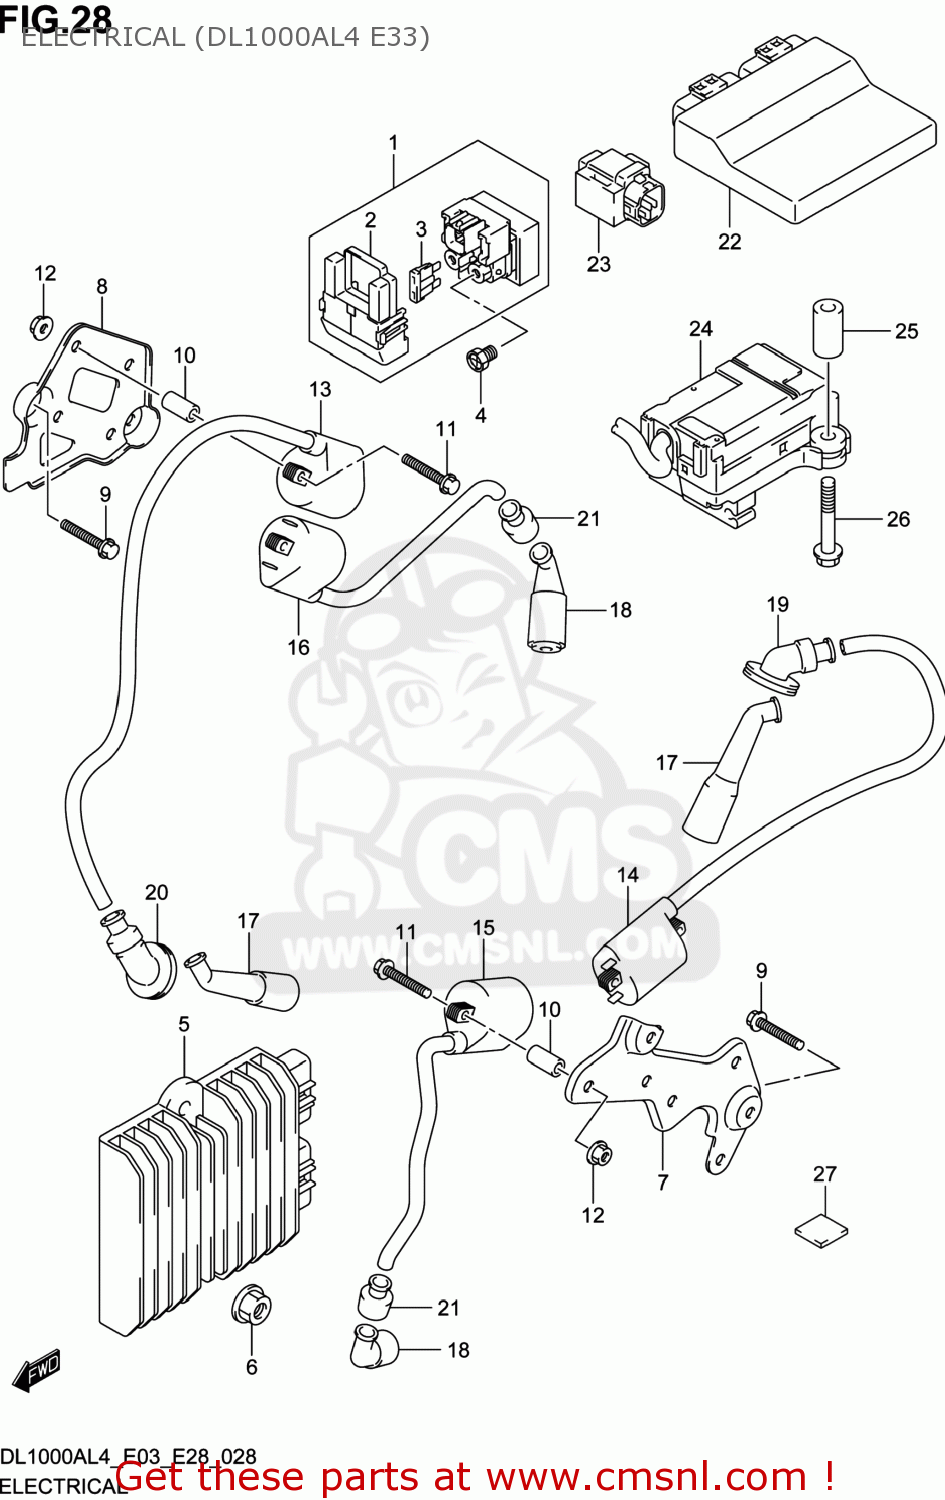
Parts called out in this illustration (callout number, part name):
1	RELAY ASSY,STARTING MOTOR
2	COVER
3	FUSE(30A)
4	SCREW(6X8)
5	RECTIFIER ASSY
6	NUT
7	BRACKET,IGNITION COIL
8	BRACKET,IGNITION COIL
9	BOLT
10	SPACER(6.4X10X18)
11	BOLT(6X35)
12	NUT
13	COIL ASSY,IGNITION
14	COIL ASSY,IGNITION
15	COIL ASSY,IGNITION
16	COIL ASSY,IGNITION
17	CAP ASSY,SPARK PLUG
18	CAP ASSY,SPARK PLUG
19	SEAL,HIGH TENSION CORD RR
20	SEAL,HIGH TENSION CORD FR
21	SEAL,HIGH TENSION CORD
22	CONTROL UNIT,FI
23	SENSOR ASSY,FUEL CUT
24	ACTUATOR ASSY,EXHAUST CONTROL
25	SPACER(6.2X14.5X26)
26	BOLT
27	CUSHION
